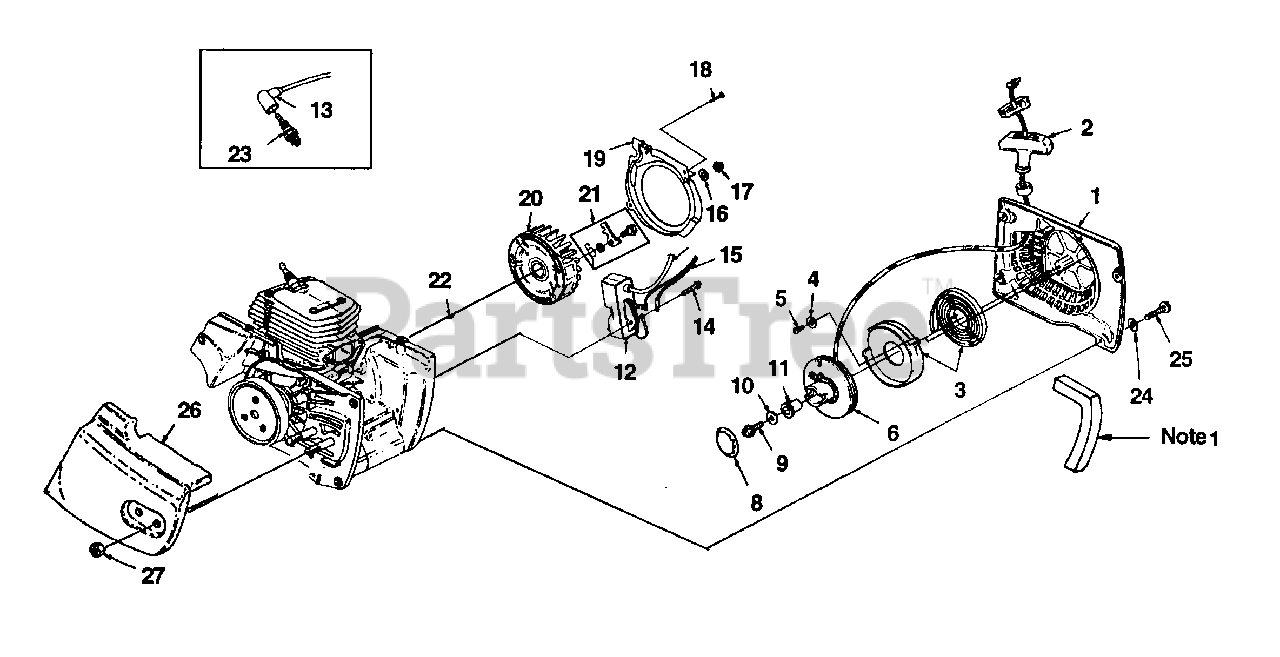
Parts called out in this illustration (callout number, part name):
1	STARTER COMPLETE
2	GRIP - w/Insert
3	SPRING & RETAINER
4	WASHER - Flat (#8)
5	SCREW - Thread Form (6 X 3/8")
6	PULLEY & ROPE
8	SPRING - Grip
9	SCREW - Plastite (10-14 X 5/8")
10	WASHER - Retaining
11	BUSHING - Starter Post
12	MODULE ASSY
13	TERMINAL - Spark Plug
14	SCREW - Hex Hd (10-24 X 7/8")
15	LEAD - Ground w/Grommet
16	WASHER - Flat
17	NUT - Lock Hex (3/8-24)
18	SCREW - Mach (8-32 X 5/8")
19	SCROLL - Air Guide
20	ROTOR
21	STARTER PAWL KIT
22	KEY - Woodruff
23	SPARK PLUG (RCJ6Y)
24	WASHER - Flat (#10)
25	SCREW - Pan Hd (10-24 X 5/8")
26	COVER - Drivecase
27	NUT - (3/8-16 x 5/16")
